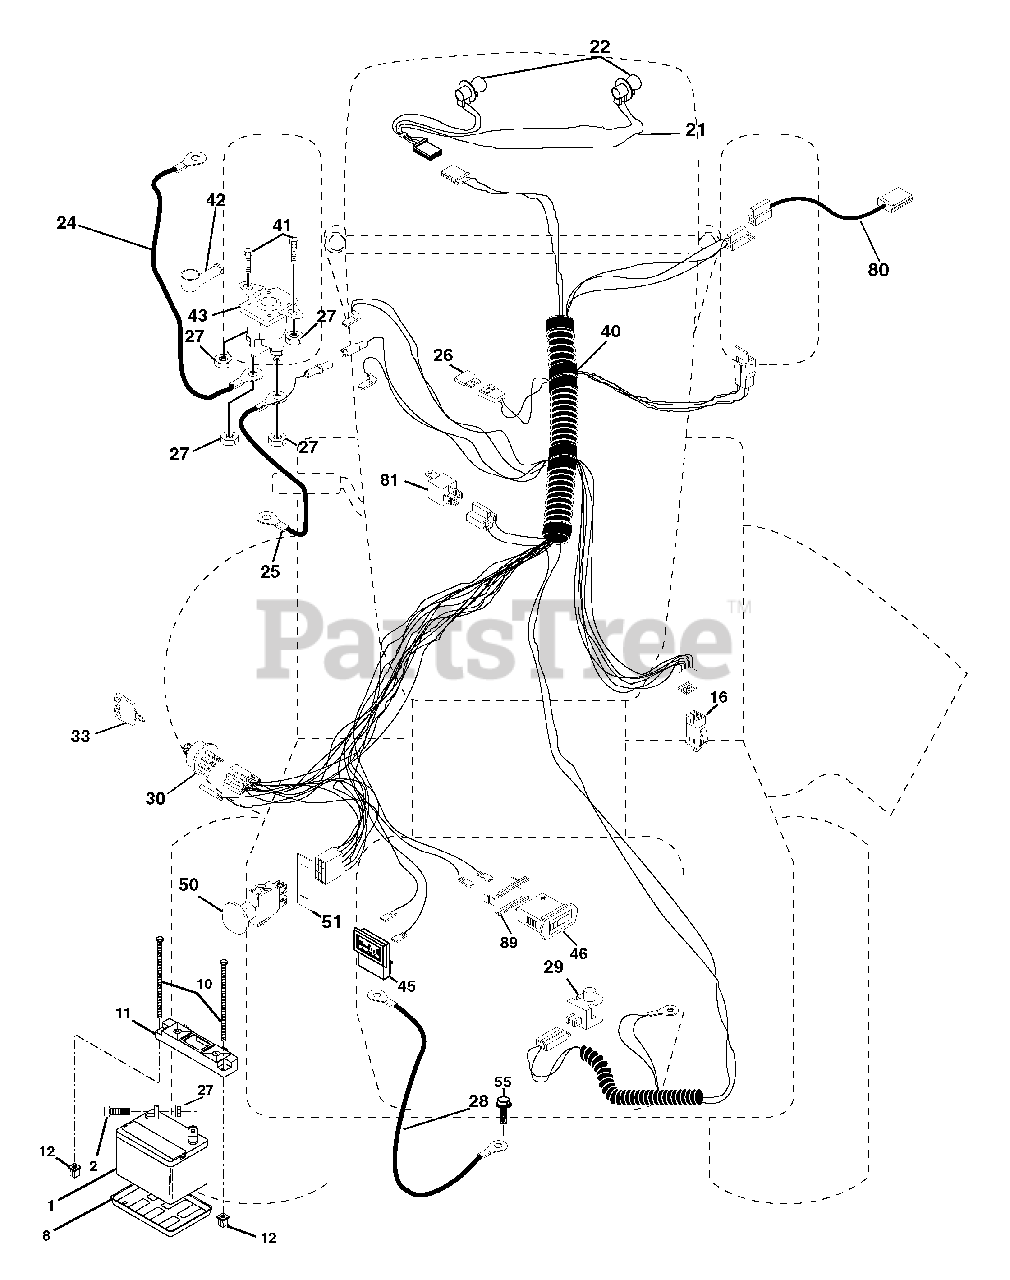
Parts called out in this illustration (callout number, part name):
1	Battery 12 Volt 25 AMP
2	Bolt Hex Hd 1/4-20unc X 3/4
8	Tray Battery
10	Bolt Brt Frt 1/4-20 x 75 Ainc
11	Holddown Battery Front Mount
12	Nut Push Nylon 1/4 Battery Frt
16	Switch Interlock Push-In
21	Harness Asm Light W/4152j
22	Bulb Light #1156
24	Cable Battery 6 Ga 22 red w/16 wire
25	Cable Battery 6 Ga 11 red
27	Nut Keps Hex 1/4-20 Unc
28	Cable Ground 6 Ga 21 black
29	Switch Plunger Nc Gray
30	Switch Ign
33	Key Ign Molded Generic
40	Harness Ign.
41	Bolt Blk Fin Hex 1/4 - 20 x 1/2
42	Cover Terminal Red
43	Solenoid
45	Ammeter Rectangular 15 Amp
46	Meter Hour
50	Switch PTO
51	Ring Retainer PTO
55	Screw Thdrol 5/16-18 x 1-1/2 Tyt
80	Harness Clutch Evx
81	Relay Asm.
89	Bracket Snap-In Hourmeter
